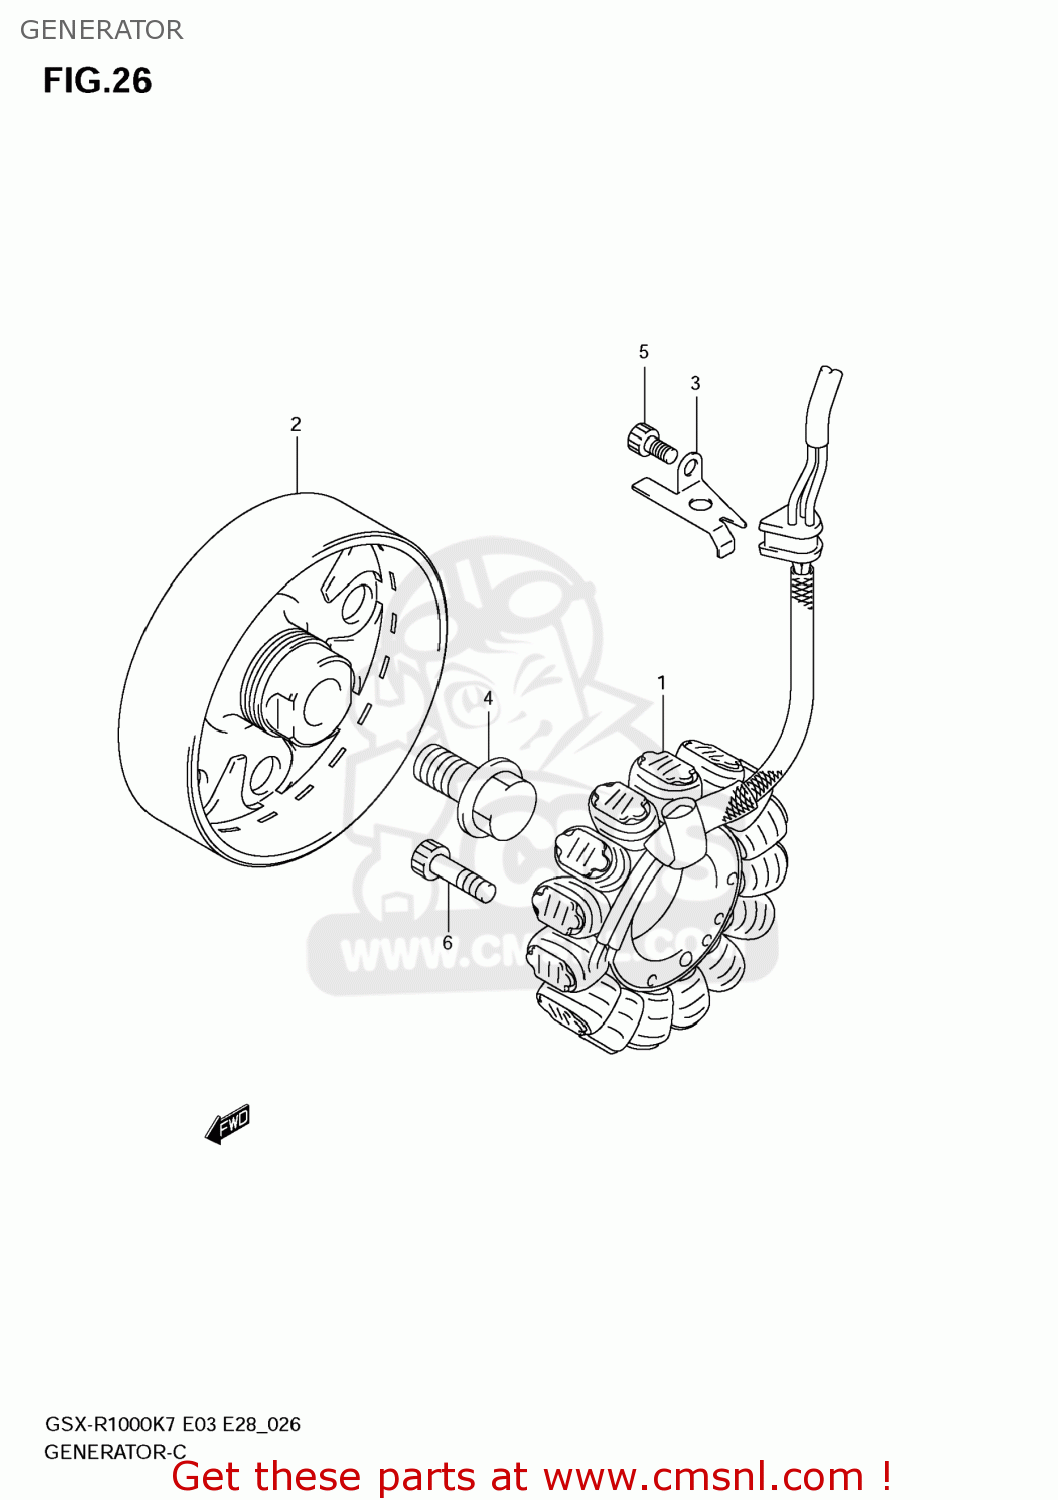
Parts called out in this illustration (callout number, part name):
1	STARTER ASSY
2	ROTOR ASSY
3	CLAMP,MAGNETO LEAD
4	BOLT(12X23)
5	BOLT
6	BOLT(6X30)
